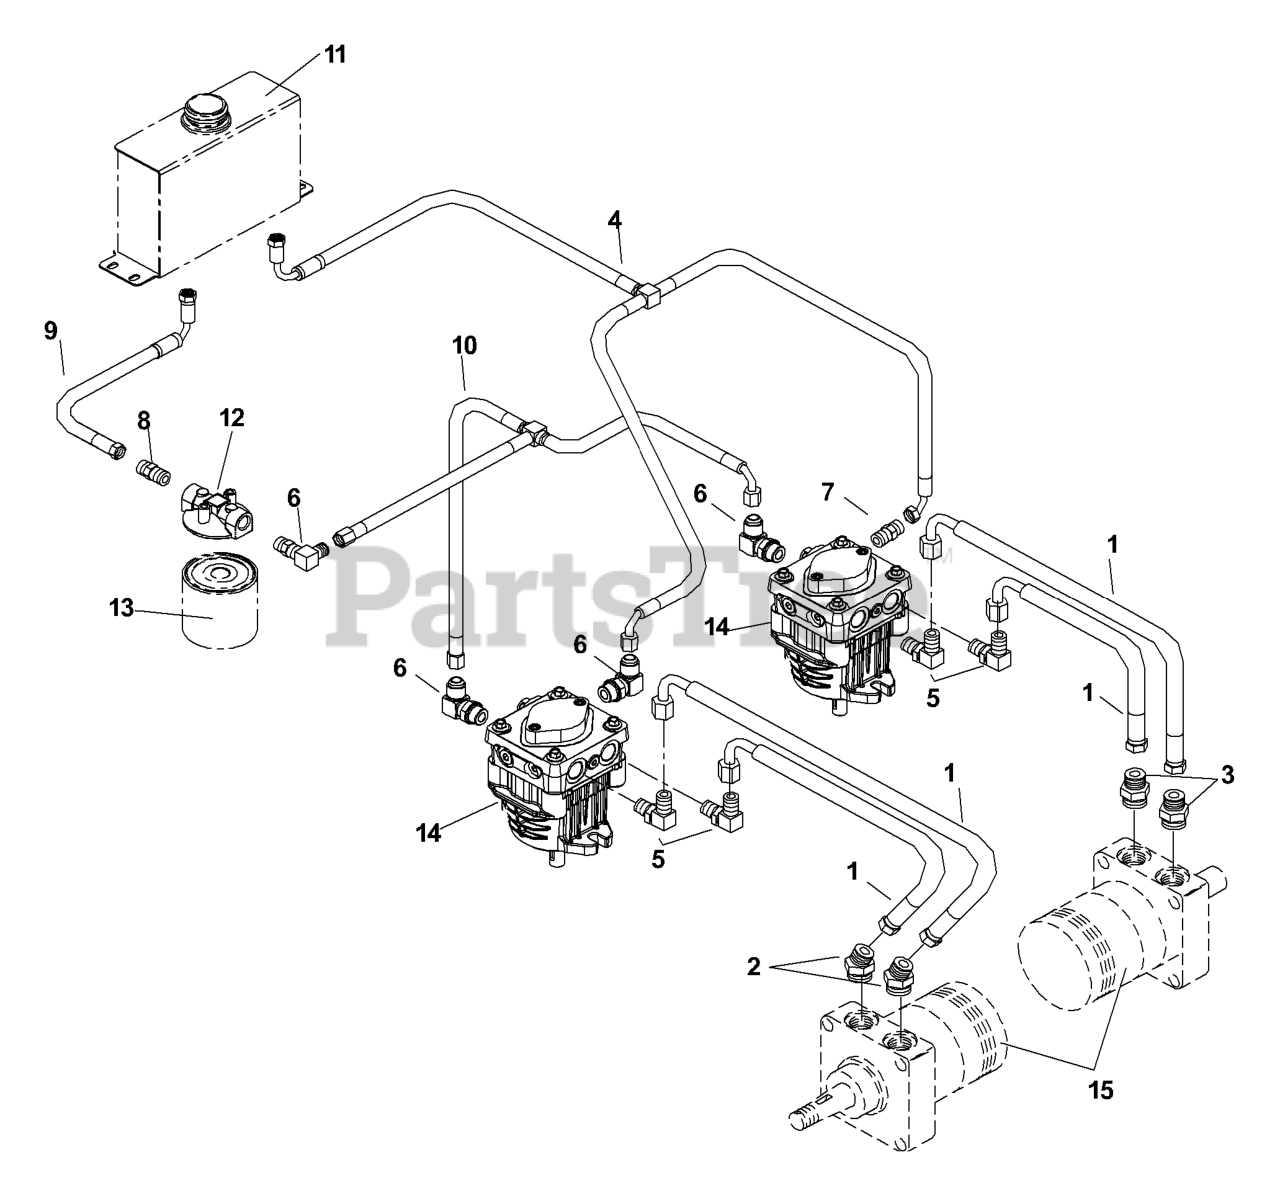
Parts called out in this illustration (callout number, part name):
1	HOSE, 1/2" HYDRAULIC
2	ELBOW-ADJ 45 DEG F6802-8-10
3	CONNECTOR, STRAIGHT
4	INLET TEE HOSE
5	ELBOW, 90 DEGREE
6	ELBOW, F6801-6-6-0 90 DEGREE
8	STRAIGHT FITG
9	HOSE
10	RETURN TEE HOSE
11	OIL TANK BLK
12	FILTER HEAD
13	HYDRAULIC OIL FILTER
14	HG_PUMP
15	WHEEL MOTOR
15	SEAL KIT - GEN I
